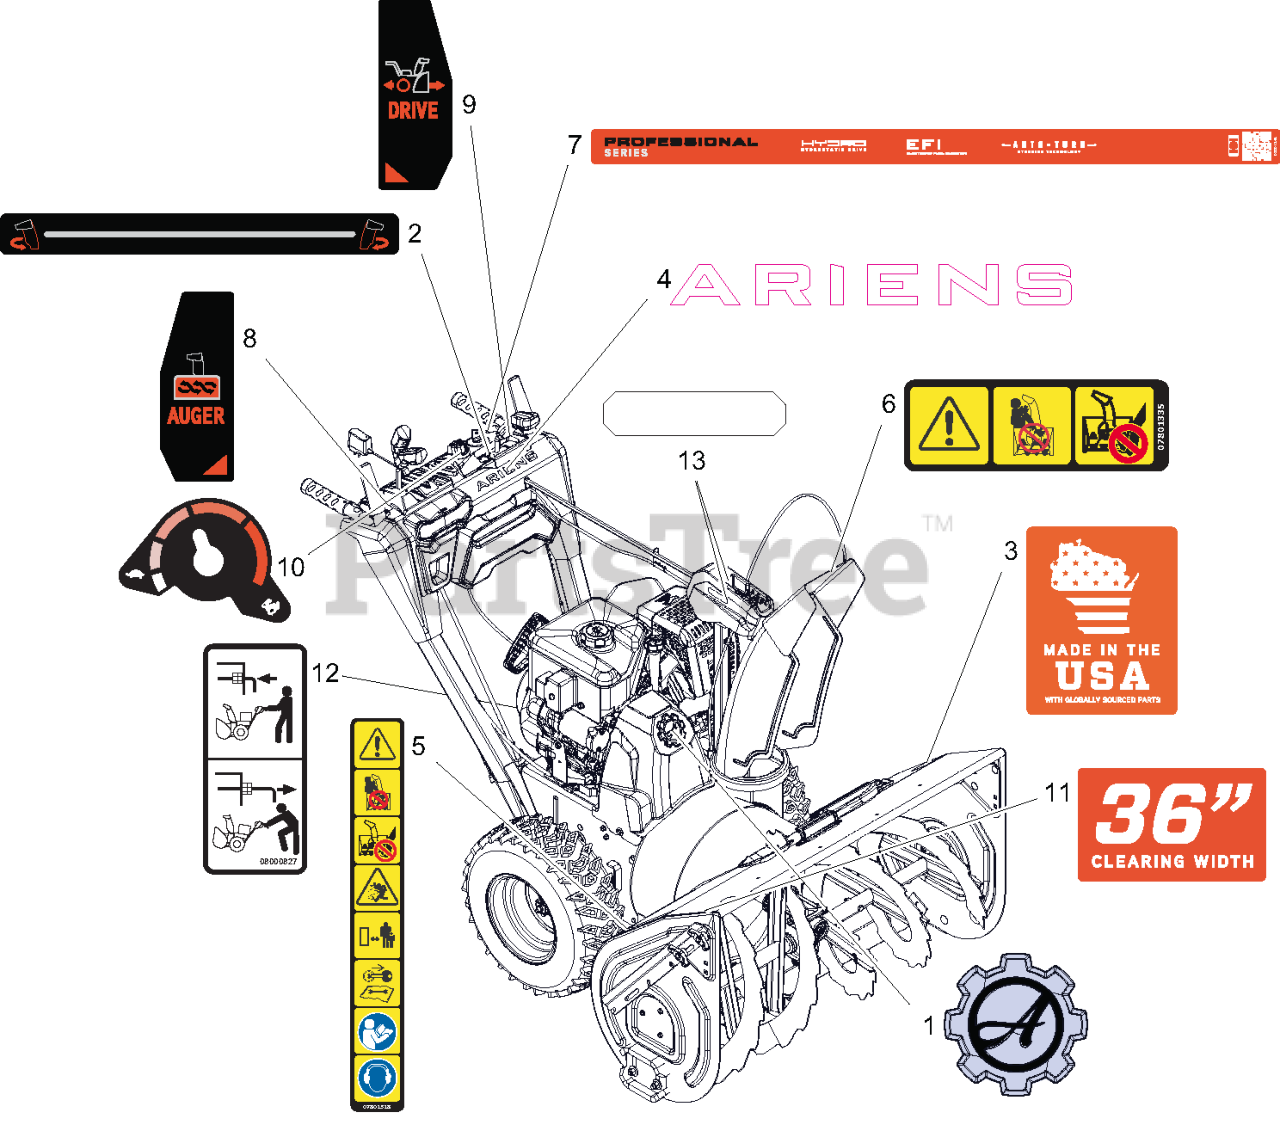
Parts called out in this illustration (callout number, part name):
1	DECAL, ARIENS - GEAR BADGE
2	DECAL- CHUTE ROTATION
3	DECAL- MADE IN USA
4	DECAL- ARIENS - 7.46"
5	DECAL- SAFETY - DANGER
6	DECAL- DANGER
7	DECAL- DASH - PRO EFI
8	DECAL- CONTROL - AUGER
9	DECAL- CONTROL - DRIVE WHEEL
10	DECAL- CONTROL - EFI SPEED
11	DECAL- CLEARING - 36
12	DECAL, BYPASS
13	DECAL,REFLECTIVE,GEAR COVER
